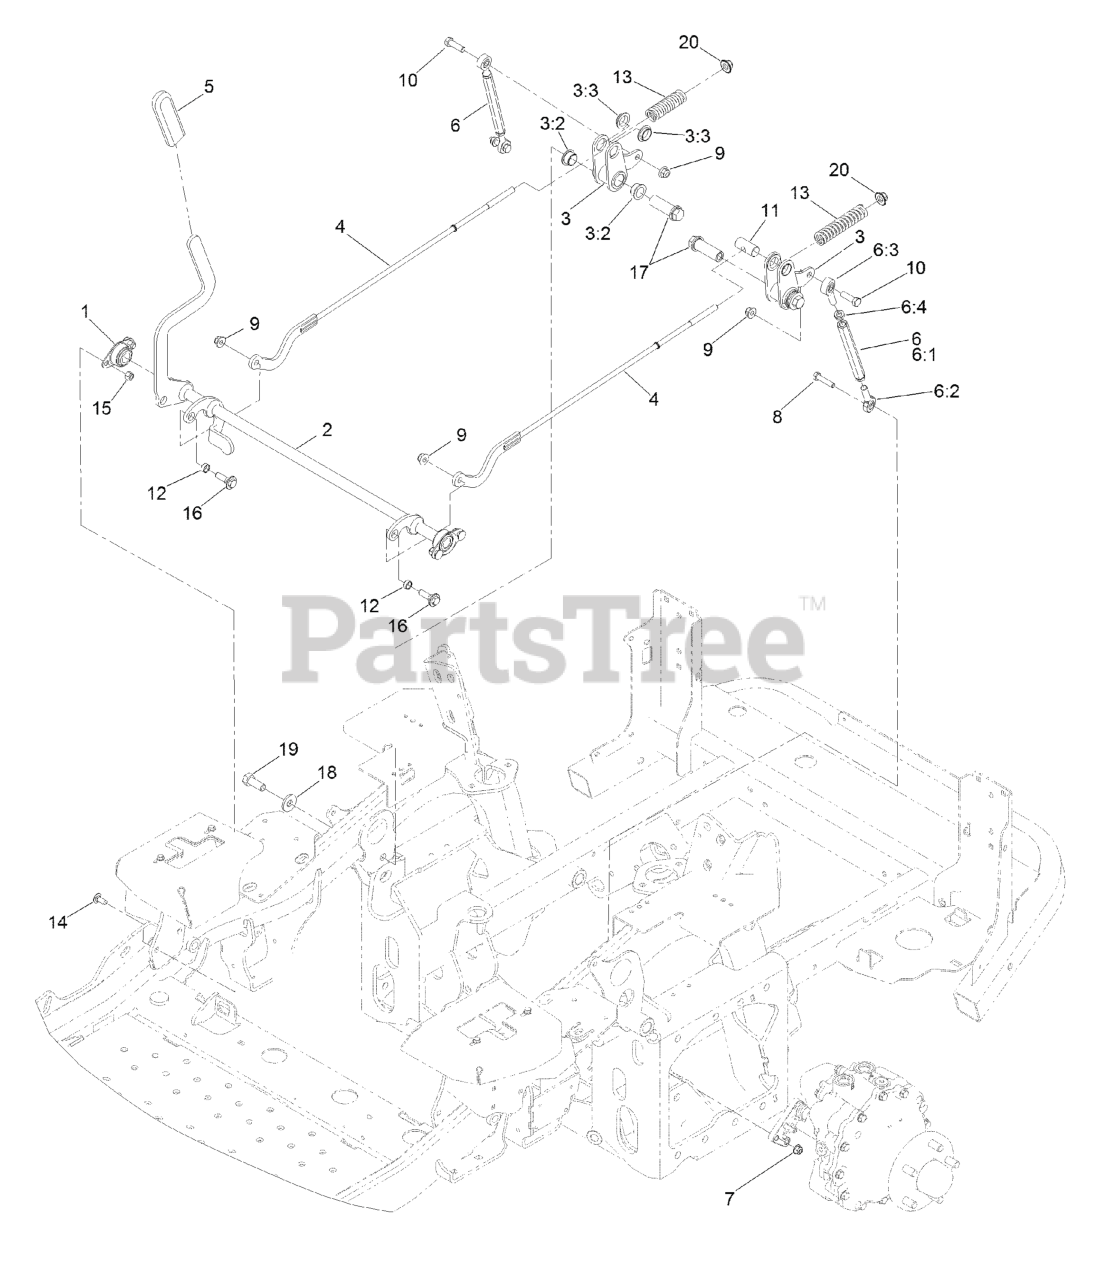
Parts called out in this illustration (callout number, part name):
1	BEARING-FLANGE, SIDE
2	SHAFT-BRAKE
3	BRAKE BELLCRANK ASM
3:2	BUSHING-FLANGE
3:3	BUSHING-FLANGE
4	LINK-BRAKE, UPPER
5	GRIP-LEVER
6	TURNBUCKLE ASM
6:1	TURNBUCKLE
6:2	BEARING-END, LH ROD
6:3	BALLJOINT
6:4	NUT-HJ
7	NUT-HF, NI
8	SCREW-HH
9	NUT-HF, NI
10	SCREW-HH
11	PIN-TRUNION
12	BEARING-SLEEVE
13	SPRING-COMPRESSION
14	SCREW-CARR
15	NUT-LOCK, NI
16	SCREW-SHOULDER, HWH
17	HUB-THREADED
18	WASHER-SPRING
19	SCREW-HH
20	Nut-Nyloc 3/8-16 Flg
